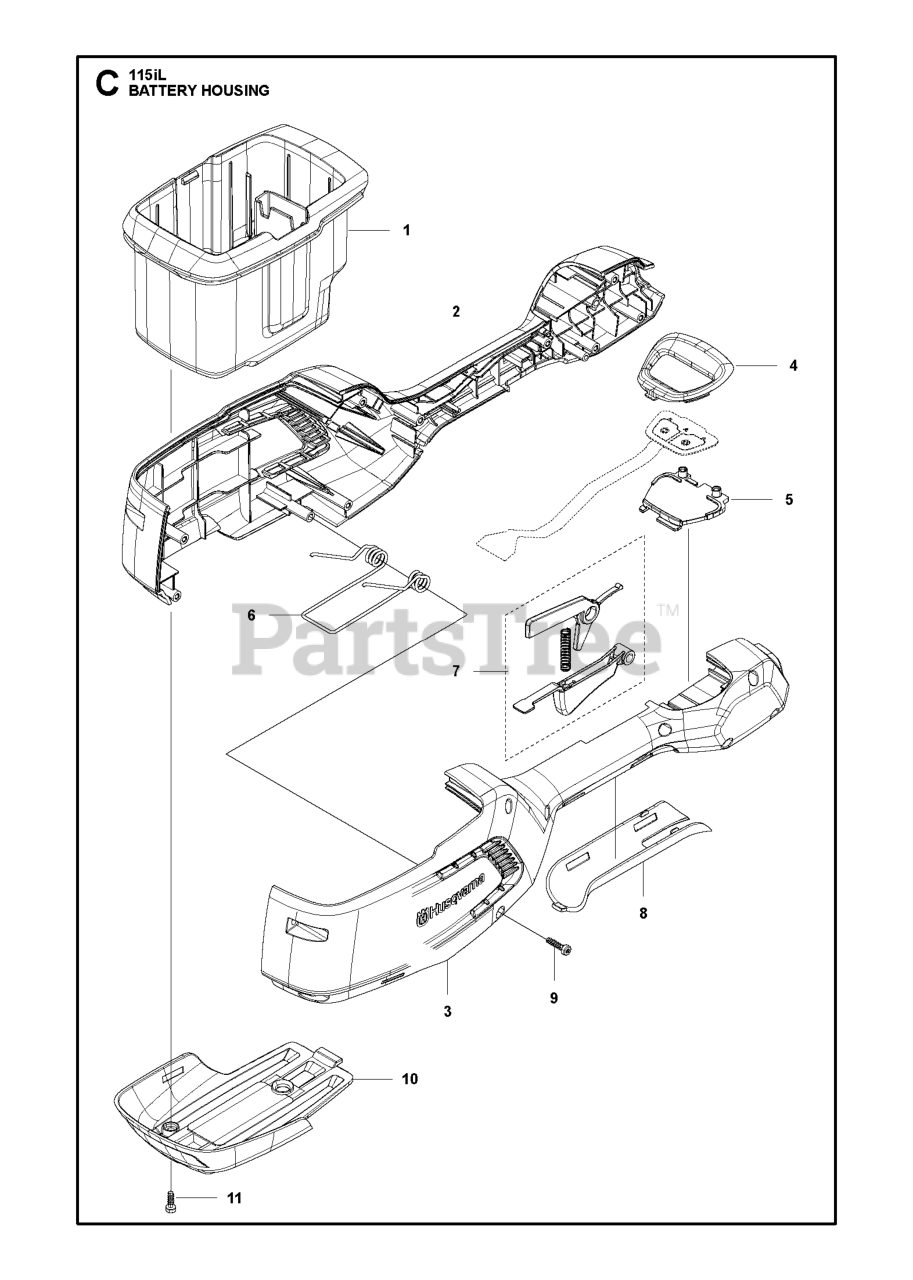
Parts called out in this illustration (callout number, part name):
1	COVER BATTERY GREY
2	HOUSING LEFT HOT FOIL 36V
3	HOUSING RIGHT HOT FOIL 36V
4	PANEL KEYPAD
5	SUPPORT KEYPAD PANEL
6	SPRING POP UP
7	TRIGGER ,TRIGGER ASSY
8	COVER REAR HANDLE GREY
9	SCREW ST4X16
10	PLATE BACK GREY
11	SCREW ST4X12
